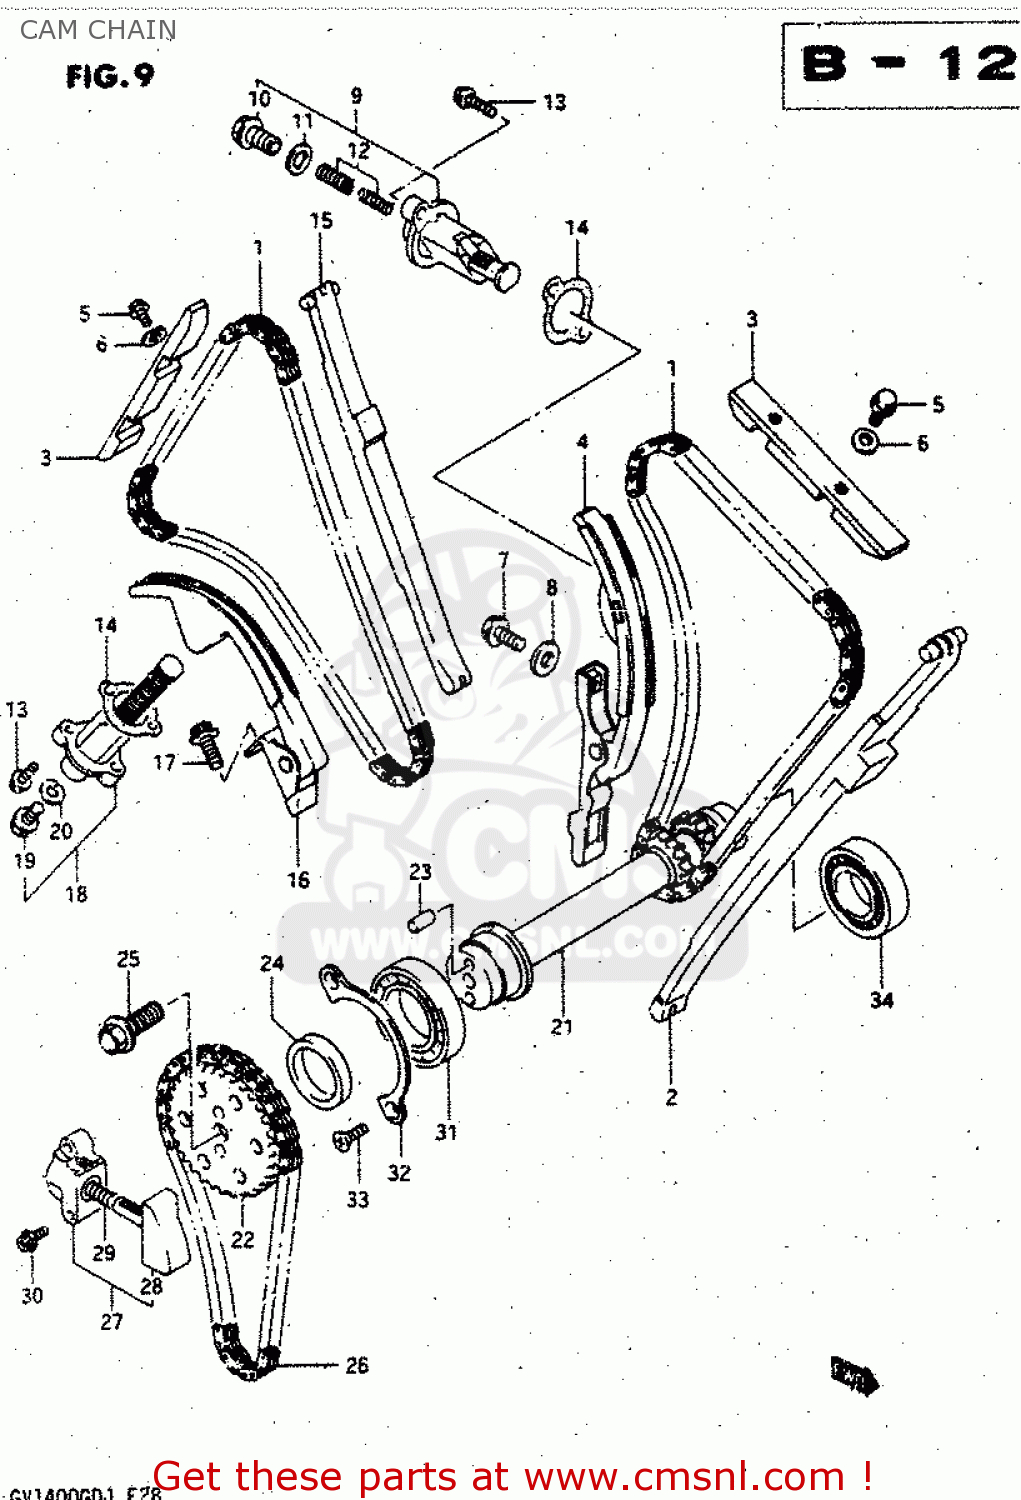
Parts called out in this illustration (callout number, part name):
1	CHAIN COMP,CAMSHAFT DRIVE
2	GUIDE,FRONT CAM CHAIN
3	GUIDE,RR CAM CHAIN NO.1
4	TENSIONER COMP,FRONT CAM
5	BOLT
6	GASKET(5.8X13X1.2) (NAS)
7	BOLT
8	GASKET (NAS)
9	ADJUSTER,FRONT TENSIONER
10	PLUG,FR TENSIONER ADJ
11	GASKET,TENSIONER ADJUSTER (NAS)
12	SPRING SET,FRONT TENSIONER
13	BOLT
14	GASKET,TENSIONER ADJUSTER (NAS)
15	GUIDE,REAR CAM CHAIN N
16	TENSIONER COMP,REAR CAM
17	BOLT
18	ADJUSTER ASSY,RR TENSIONER
19	PLUG
20	GASKET,TENSIONER ADJUSTER (NAS)
21	SHAFT, IDLER
22	SPROCKET,IDLER SHAFT
23	PIN(6X14)
24	SPACER
25	BOLT(10X24)
26	CHAIN,IDLER SHAFT,DRIVE
27	ADJUSTER,IDLE CHAIN
28	BOLT,ADJUST OIL HOSE UNION
29	PLUG,ADJUSTER
30	BOLT
31	BALL BEARING 32X58X13
32	WASHER
33	SCREW
34	ROLLER BEARING (20X47X
